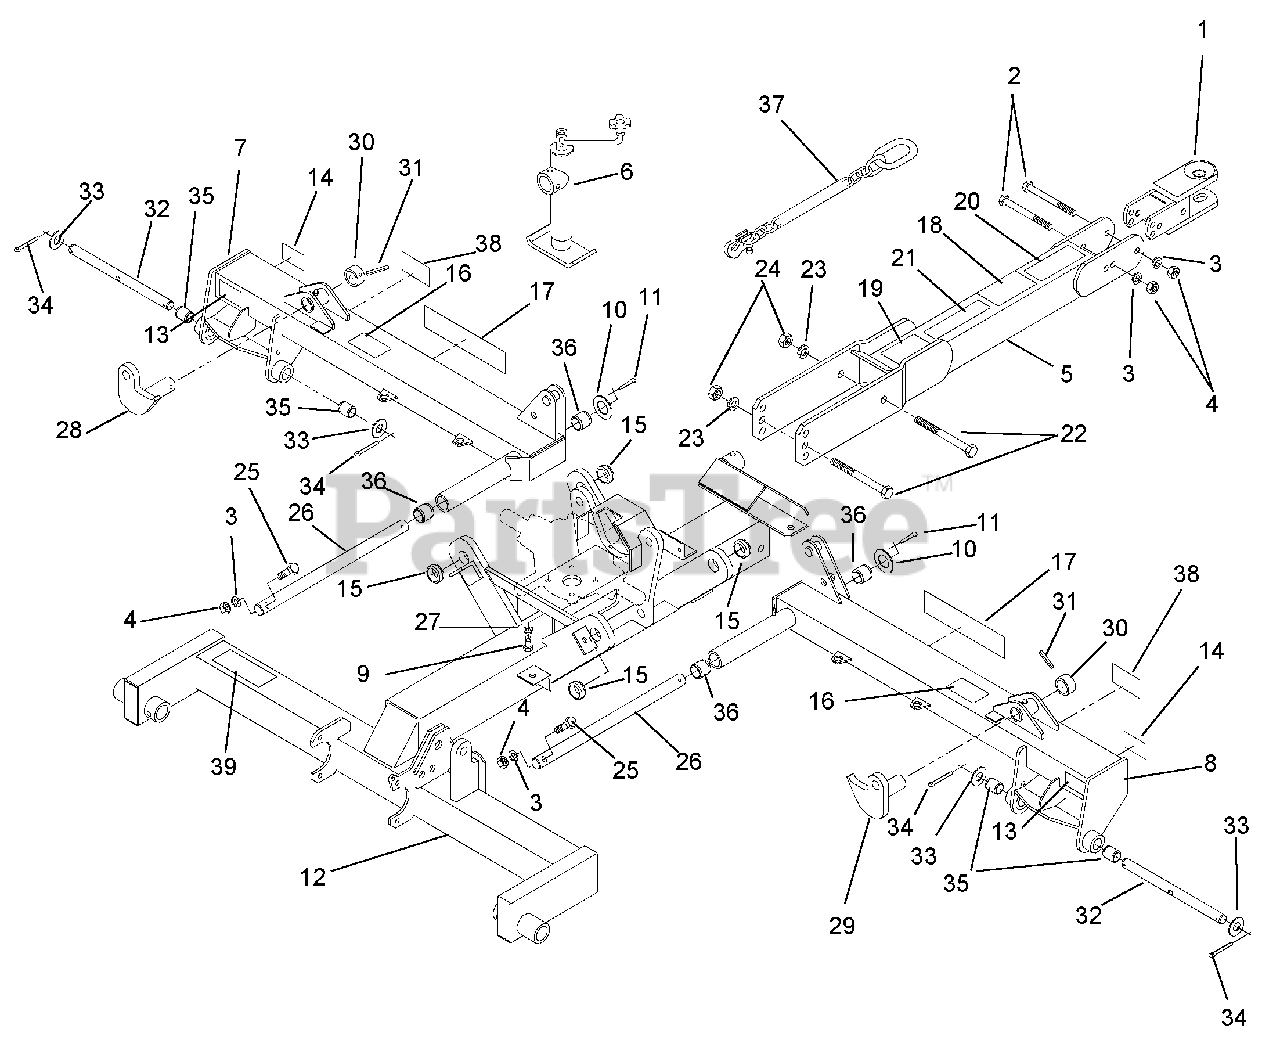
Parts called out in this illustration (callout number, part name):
1	Weldment, Hitch
2	Cap Screw, Hex Head .625 x 6
3	Washer, Lock .625
4	Nut, Hex .625
5	Tongue With Decals
6	Jack Assembly
7	Assembly, Wing With Decals LH
8	Assembly, Wing With Decals, RH
9	Cap Screw, Hex Head M12 x 1.75
10	Washer, Flat 1.25
11	Cotter Pin .25 x 1.75
12	Weldment, Frame
13	Reflector, Red
14	Reflector, Amber
15	Bushing, Spring 1.50 x 1.25
16	Decal, Warning
17	Decal, 9.5-Inch Gravely Logo
18	Decal, Warning
19	Decal, Drawbar
20	Decal, Important
21	Decal, Caution 540 RPM
22	Cap Screw, Hex Head .75-10 x 7
23	Washer, Lock .75
24	Nut, Hex .75-16
25	Cap Screw, Hex Head .625-11 x 2.5
26	Pin, Pivot
27	Washer, Lock .50
28	Weldment, Swivel LH
29	Weldment, Swivel RH
31	Pin, Roll 3/8 x 2-1/2
33	Washer, Flat 1.00
34	Pin, Cotter .25 x 1.75
35	Bushing, Spring 1.25 x 1 x 1.50
36	Bushing, Spring 1.50 x 1.25
37	Chain, Safety Toe
38	Decal, Float Information
39	Decal, Lubrication Chart
